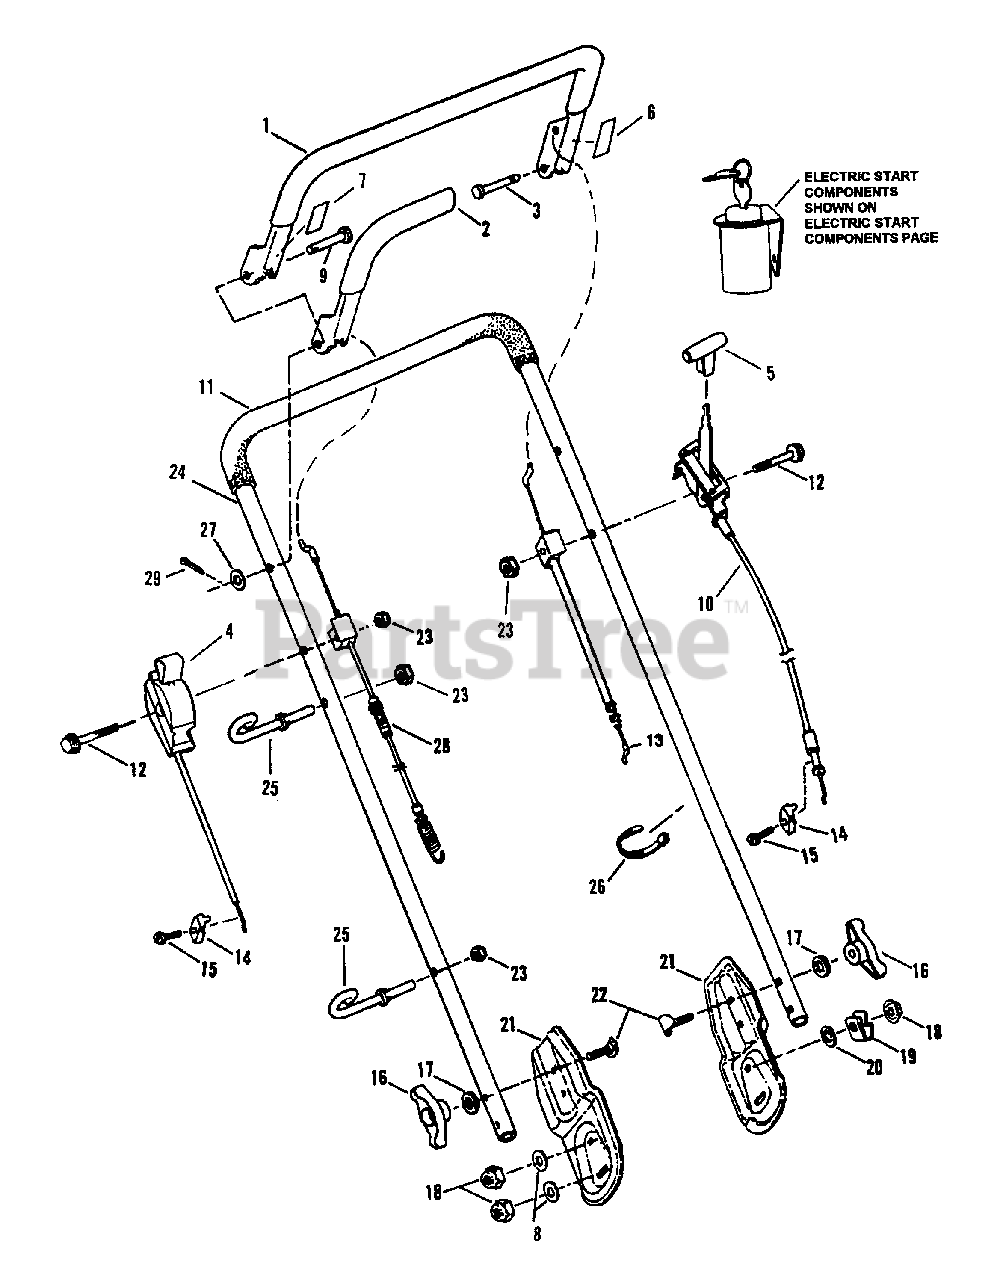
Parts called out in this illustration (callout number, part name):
1	CONTROL, Blade
2	CONTROL, Ground Speed
3	PIN, 5/16 x 1-7/16" Clevis
4	CONTROL, Engine Speed
5	KNOB, Engine Speed & Ground Speed Control
6	DECAL, 3-Speed Control
7	DECAL, Engine Speed
8	WASHER, 11/32" Flat
9	PIN, 5/16 x 1-23/32" Clevis
10	CONTROL, Ground Speed
11	GRIP, Foam
12	SCREW, 1/4-20 x 2-1/4" Hex Washer Head, Self-Tapping
13	CABLE ASSEMBLY, Blade Control
14	CLAMP, Engine Speed (3-Speed Control)
15	SCREW, #10-32 x 5/8" Slotted Hex Head, Self-Tapping
16	KNOB, 5/16-18 Thread
17	WASHER, 5/16 Internal Tooth Lock
18	NUT, 5/16-18 Hex Nyloc
19	CLAMP, Double Tube
20	RETAINER, 5/16 Bolt
21	BRACKET, Handle
22	SCREW, 5/16-18 x 2" Curved Head
23	NUT, 1/4-20 Hex Nyloc
24	HANDLE, Upper
25	GUIDE, Rope
26	TIE, Wire
27	WASHER, Flat, .11/32 I.D. x 11/16 O.D.
28	CABLE, Traction
29	COTTER-PIN, 3/32" x 1/2"
